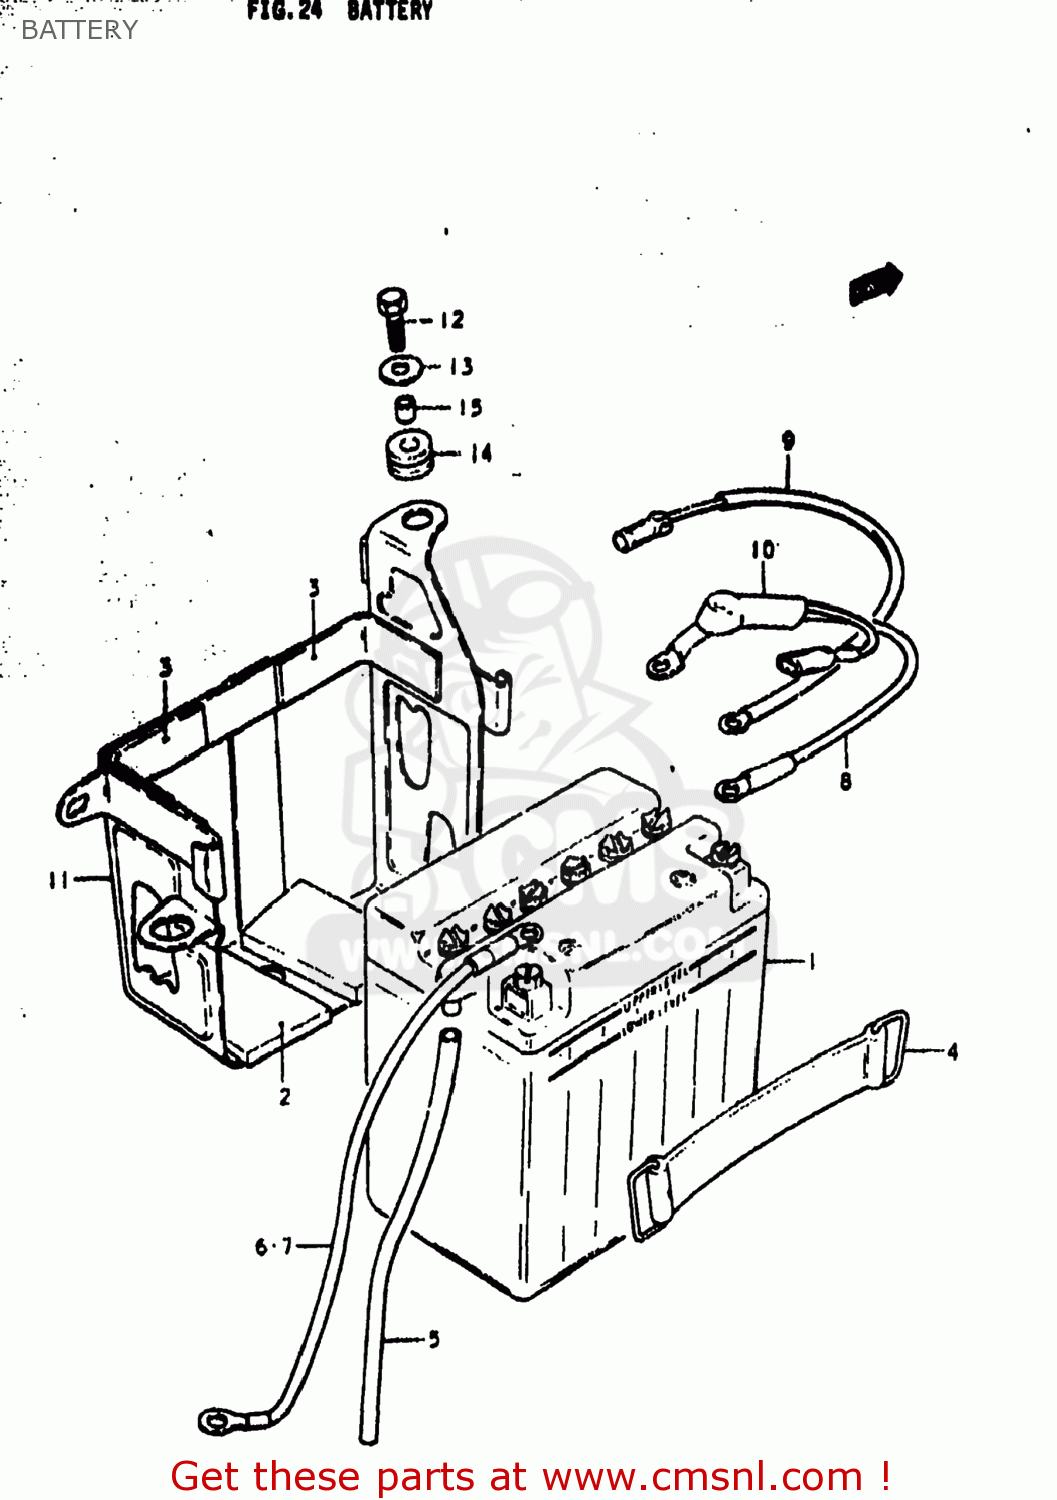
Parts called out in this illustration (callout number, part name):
1	BATTERY ASSEMBLY
2	CUSHION,BATTERY
3	PROTECTOR,20X9
4	BAND
5	HOSE,BATTERY EXHAUST
6	CORD,BATTERY MINUS
7	WIRE
8	WARE,BATTERY PLUS
9	WIRE
10	CAP,TERMINAL
11	HOLDER,BATTERY
12	BOLT
13	WASHER
14	CUSHION
15	SPACER (6.1X9X9)
